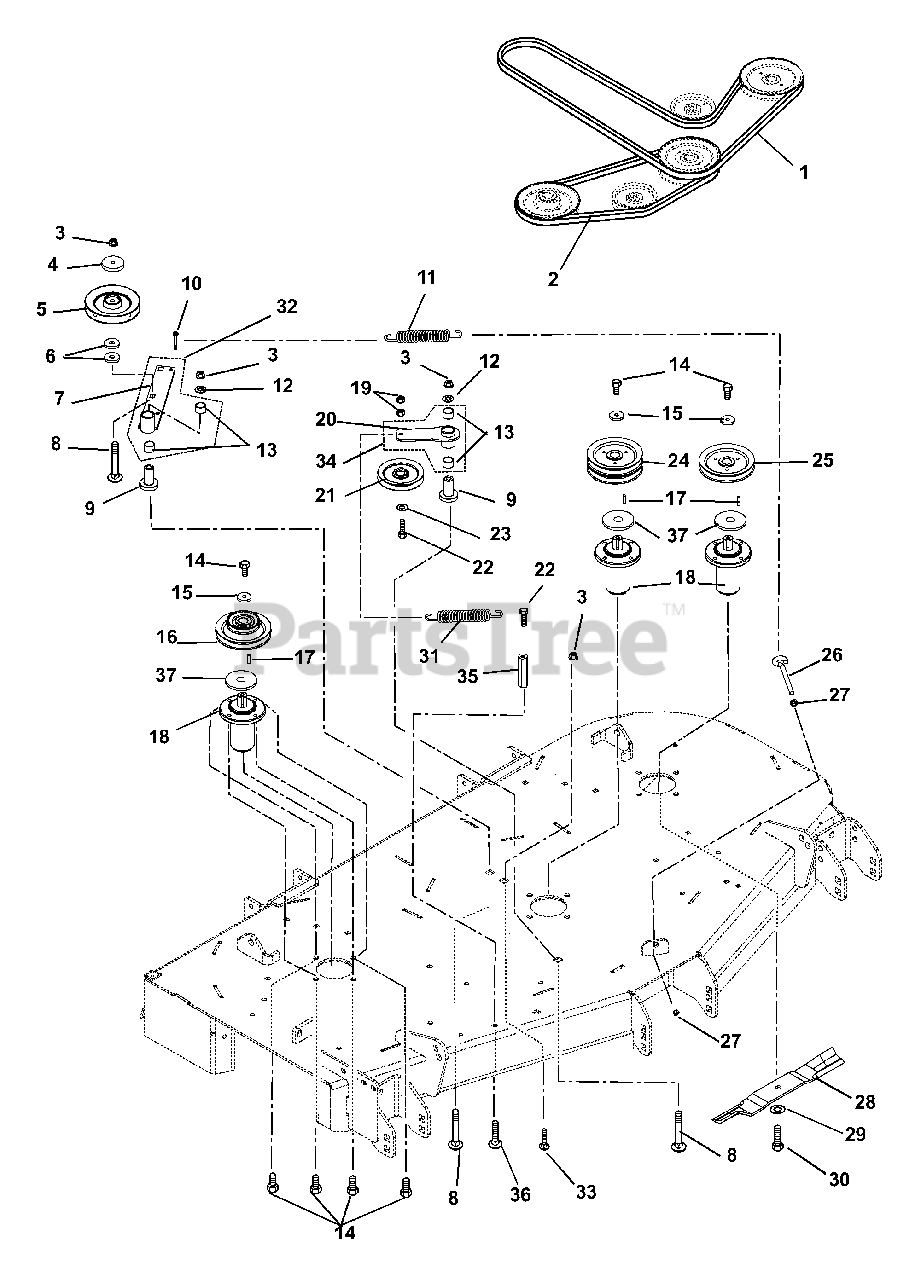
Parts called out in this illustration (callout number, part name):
1	Belt, 118.00" Long, PTO Drive Hex (991009, 015)
1	Belt, 114.50" Long, PTO Drive Hex (991010, 016, 021)
1	Belt, 120.50" Long, PTO Drive Hex (991011, 017, 018)
1	Belt, 130.00" Long, PTO Drive Hex (991013, 019, 020)
2	V-Belt, 51.18" Long Cog B-Section (991009, 010, 015, 016, 021)
2	V-Belt, 56.00" Long Cog B-Section (991011, 017, 018)
2	V-Belt, 63.00" Long Cog B-Section (991013, 019, 020)
3	Nut, .50-13 Nyloc Flange
4	Cap, Idler Bearing Sealing
5	Pulley, V 6.0 x .500 ID DBL. Bearing
6	Washer, Flat Stee,l .515 x 1.625 x .250
7	Idler, Pivot Arm
8	Bolt, Round Head Square Neck .50-13 x 3.50
9	Bearing, Pedestal
10	Bolt, Shoulder EP .38-16 x .30 Hex
11	Spring, Extension (Deck Idler)
12	Washer, Flat Steel .531x 1.250 x.100
13	Bearing, 1.00 x 1.12 x .75
14	Bolt, Hex .38-16 x 1.00
15	Washer, Flat Steel .406 x 1.50 x .245
16	Sheave, Double, 1" ID x 5.44" OD x 3.50" OD (991009, 010, 015, 016, 021)
16	Sheave, Double, 1" ID x 6.00" OD and 3.50" OD (991011, 017, 018)
16	Sheave, Double, 1" ID x 6.75" OD and 4.25" OD (991013, 019, 020)
17	Key, Square .25 x .25 x 1 RC 40-50
18	Spindle Assembly
19	Nut, Locking-Center .38-16
20	Idler, Pivot Arm
21	Sheave, .38" ID x 5" OD
22	Bolt, Hex .38-16 x 2.25
23	Washer, Flat Steel .406 x .812 x .065
24	Sheave, Double 1" ID x 5.44" OD (991009, 010, 015, 016, 021)
24	Sheave, Double 1" ID x 6.00" OD (991011, 017, 018)
24	Sheave, Double 1" ID x 6.75" OD (991013, 019, 020)
25	Sheave, Single 1" ID x 5.44" OD (991009, 010, 015, 016, 021)
25	Sheave, Single 1" ID x 6.00" OD (991010, 016, 021)
25	Sheave, Single 1"ID x 6.75" OD (991013, 019, 020)
26	Bolt, .38-16 x 4.00 .62 Diameter Eye
27	Nut, Hex, Jam .375-16
28	Blade, Mower, 44 in. & 48 in. Decks (991009, 010, 015, 016, 021)
28	Blade, Mower, 52 in. Decks (991011, 017, 018)
28	Blade, Mower, 60 in. Decks (20.50") (991013, 019, 020)
29	Washer, Bellville .63 x 1.625 x.14
30	Bolt, Hex .62-18 x 1.75 Grade 8
31	Spring, Extension
32	Assembly, PTO Idler Pivot Arm
33	Bolt, Round Head Square Neck .50-13 x 1.5, Full Thread, Grade 5
34	Assembly, Idler Pivot Arm
35	Nut, Coupling .375-16 x 1.75
36	Bolt, Round Head Square Neck .38-16 x 1.00
37	Slinger, Dust
